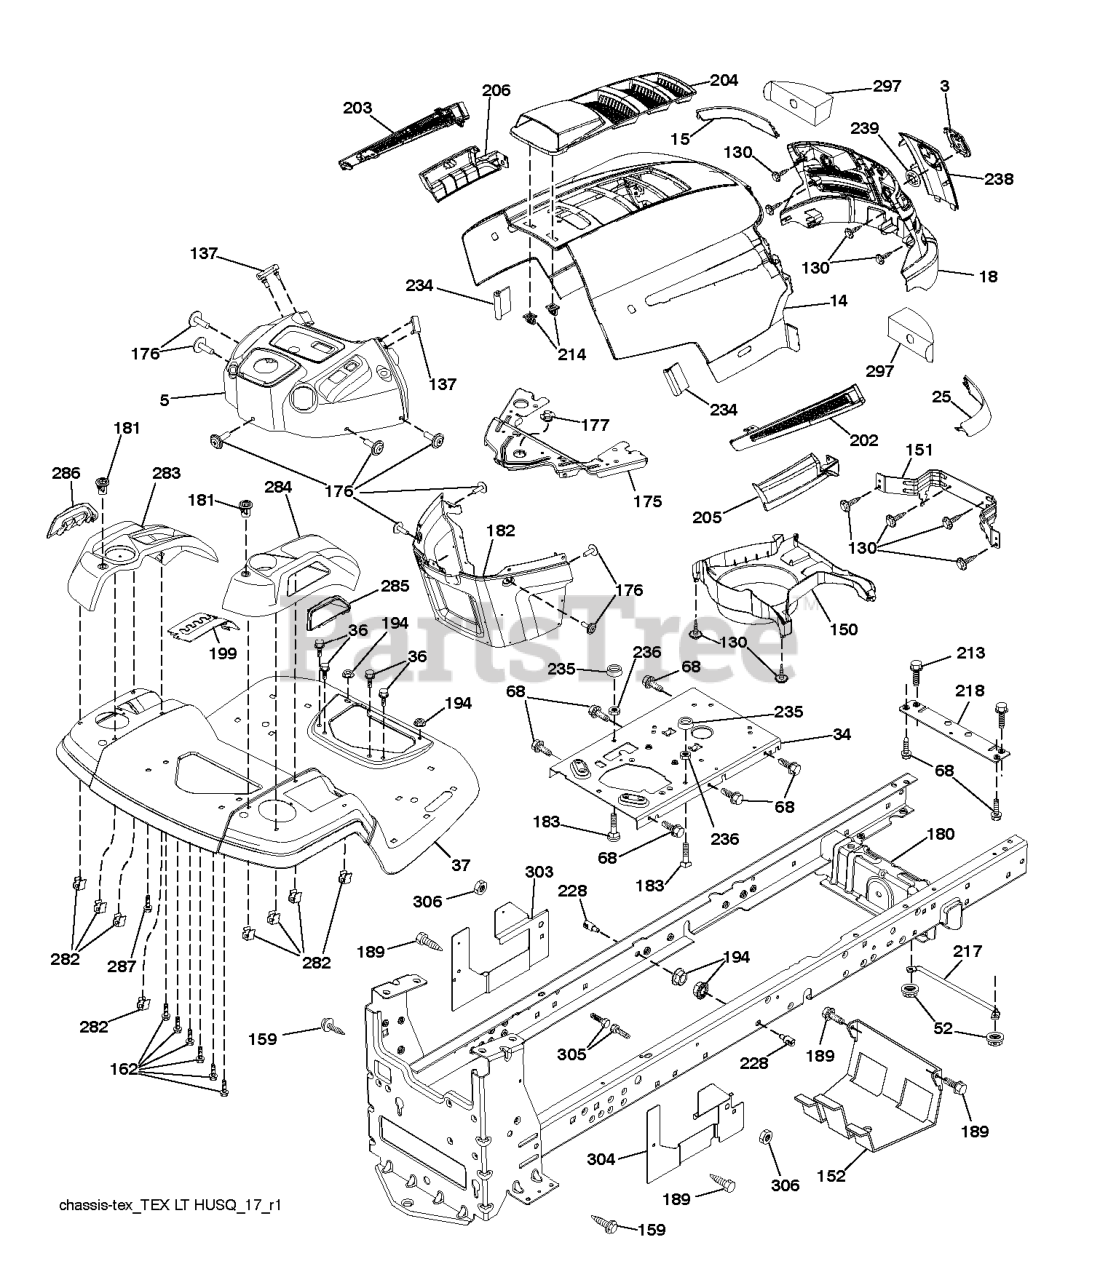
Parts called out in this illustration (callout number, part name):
3	RP LOGO
14	HOOD
15	LENS.HUSQVARNA LT.LH
18	RP GRILLE/LENS ASM.
25	LENS.HUSQVARNA LT.RH
34	PLATE.ENGINE.WELDED.CHASSIS
36	SCREW 3/8-16X3/4
37	RP FENDER.TLT.FS.W/CPH.422
52	LOCKNUT
68	Screw 5/16-18 x 1/2 Hex, Self Tapping 5/16-18 x 1/2
130	SCREW.#10 X 0.750.BOS
137	BUMPER DASH
151	BRACKET PIVOT
152	SHIELD.BROWNING.W/TEX
159	SCREW, 3/8-16X3/4
162	SCREW.HI-LO.CONSOLE
175	CROSSMEMBER
176	SCREW.#10-24X5/8.RN.QU
177	BUSHING STEERING
180	CHASSIS
181	BUSHING.MNT.FEND.CRGO.
182	DASH.LOWER.PREDATOR LT
183	BOLT.5/16-18X1-1/4 FULL.THREAD
189	SCREW
191	INSERT.REFLECTIVE.RH.
194	NUT LOCK HEX FLANGE 5/16-18
199	PLATE.DECK.LIFT.HUSQ.LT
202	VENT SIDE HOOD RH
203	VENT SIDE HOOD LH
204	VENT TOP HOOD
205	SKIRT SIDE RH
206	SKIRT SIDE LH
213	BOLT
214	CLIP.RETAINER.TINNER.
217	ROD.PIVOT.HOOD
218	X-PIECE.HOOD.STOP.NON/
228	STUD.FASTNER.W/ANTI-ROTATE
234	BUMPER.HOOD.TEX.HUSQVARNA
235	SPACER FENDER
236	NUT.CENTERLOCK.5/16-
238	TRIM
282	CLIP.RETAINER.CONSOLE.LT.HUSQ
283	CONSOLE.DECK.LIFT.HUSQ.N/FR.GR
284	CONSOLE.SHFT.HYD,HUSQL
285	CONSOLE INSERT RH
286	CONSOLE.INSRT.LH.HUSQ.LT.BLACK
287	SCREW 1/4X20
297	INSERT REFLECTIVE
303	SHIELD CHASSIS LEFT
304	SHIELD CHASSIS RIGHT
306	NUT LOCK FLG 3/8-16 UNC
